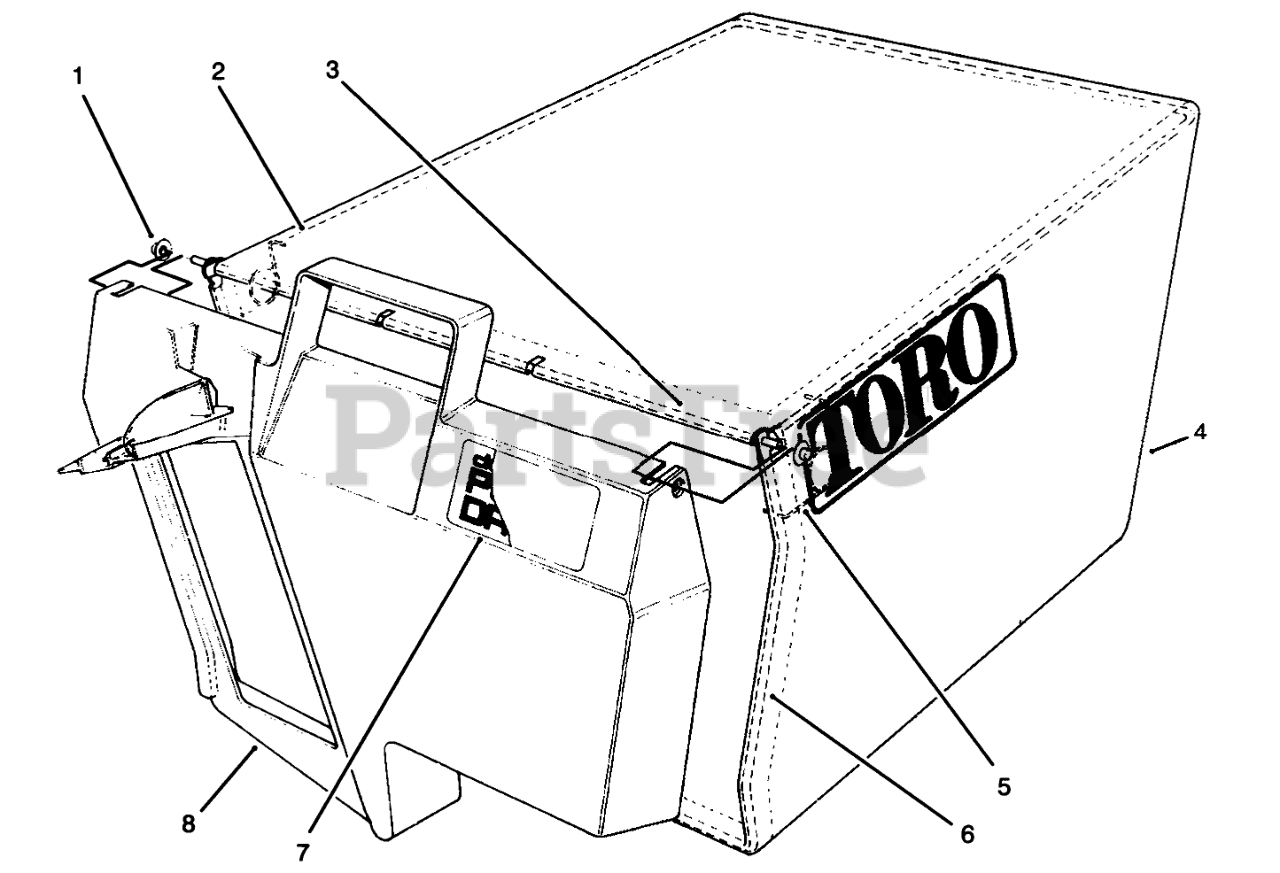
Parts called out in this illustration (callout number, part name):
1	NUT-PUSH
2	FRAME-BAG, UPPER
3	HINGE-DOOR, BAG
4	Bag
5	SPRING
6	FRAME-BAG
7	BAG DOOR DECAL
8	DOOR-BAG
